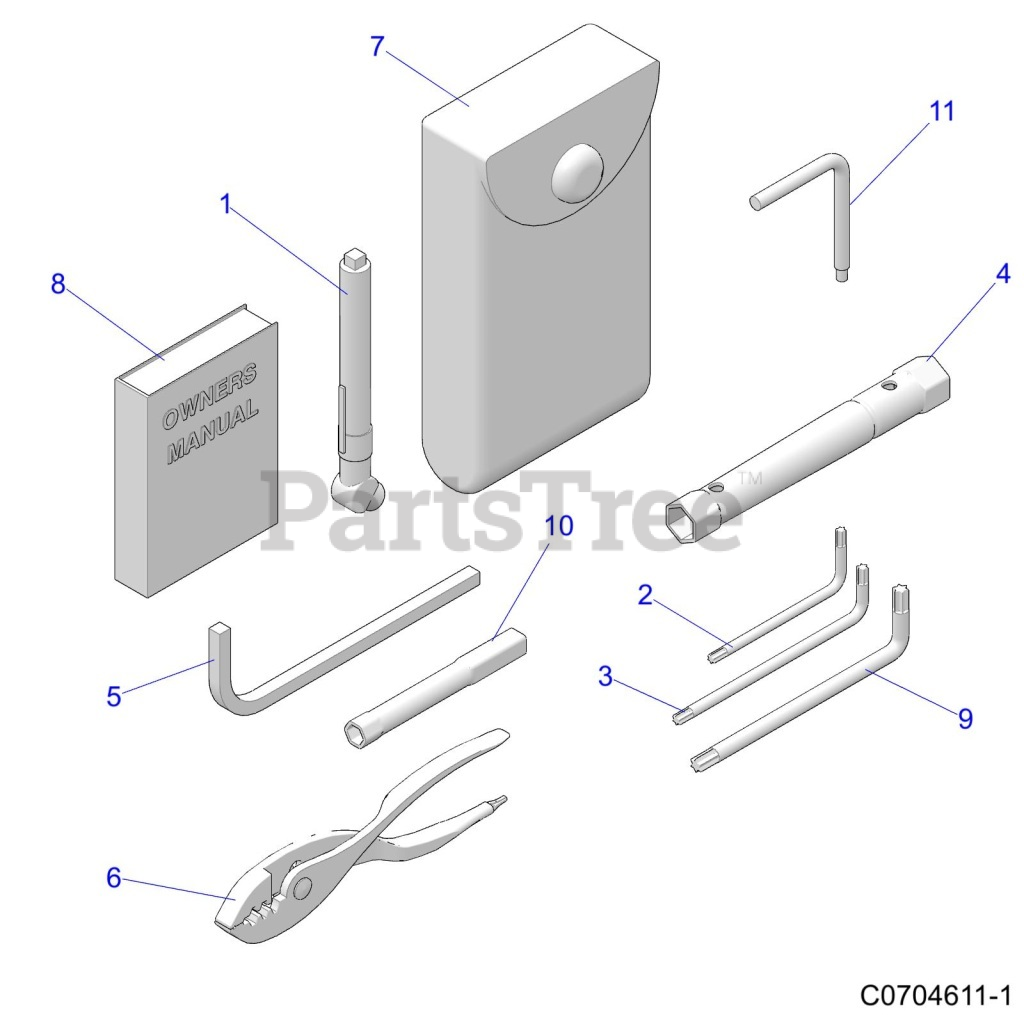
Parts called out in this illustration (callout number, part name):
1	GAUGE-TIRE PRESSURE,30 PSI
2	WRENCH-TORX,T-25
3	SOCKET-SPARK PLUG,14/16MM
4	SOCKET-SPARK PLUG,14/16MM
4	SOCKET-SPARK PLUG
5	HANDLE, SPARK PLUG
6	PLIERS-COMBO, #2 ASSEMBLY
7	POUCH,TOOLKIT,9"
8	MAN-OWN,20 ARNS/CREW,1K
9	WRENCH-TORX,T-40
10	Driver Nut 8 MM
11	TOOL-BELT REMOVAL
